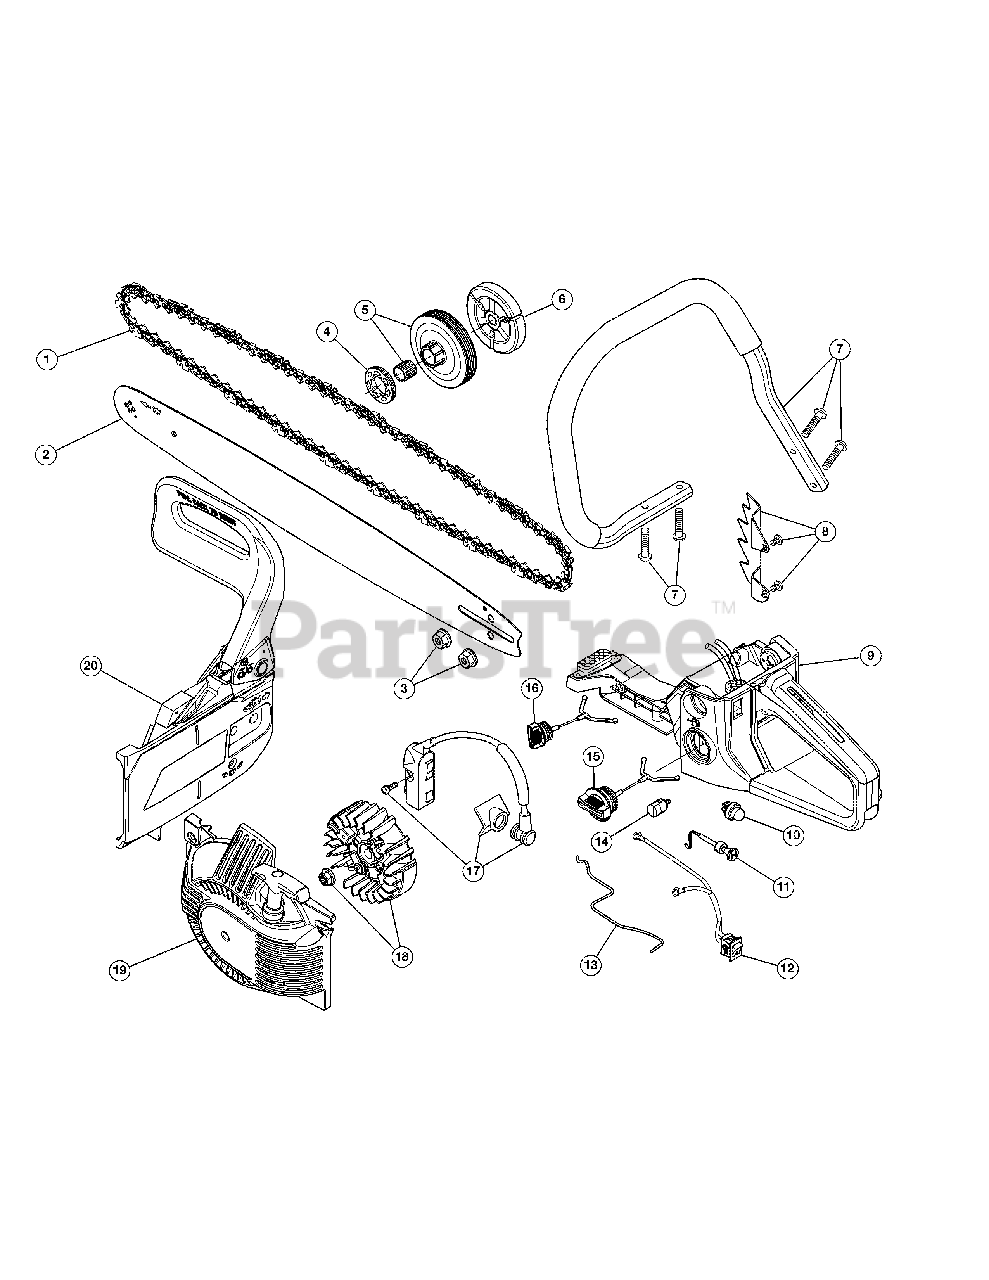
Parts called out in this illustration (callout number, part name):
1	Saw Chain 18" (for RM4618)
1	Saw Chain 20" (for RM4620)
2	Guide Bar 18" (for RM4618)
2	Guide Bar 20" (for RM4620)
3	Guide Bar Nuts (2)
4	Sprocket
5	Clutch Drum Assembly
6	Clutch Assembly
7	Chainsaw Handle Assembly (with Screws (4))
8	Spike Plate (with Screws (2))
9	Fuel Tank Assembly
10	Primer Bulb
11	Choke Lever Assembly
12	Stop Switch Assembly
13	Throttle Rod
14	Fuel Filter
15	Fuel Cap Assembly
16	Oil Cap Assembly
17	Ignition Module Assembly (with Screws (2))
18	Flywheel Assembly
19	Starter Housing Assembly
20	Chainsaw Brake Assembly
